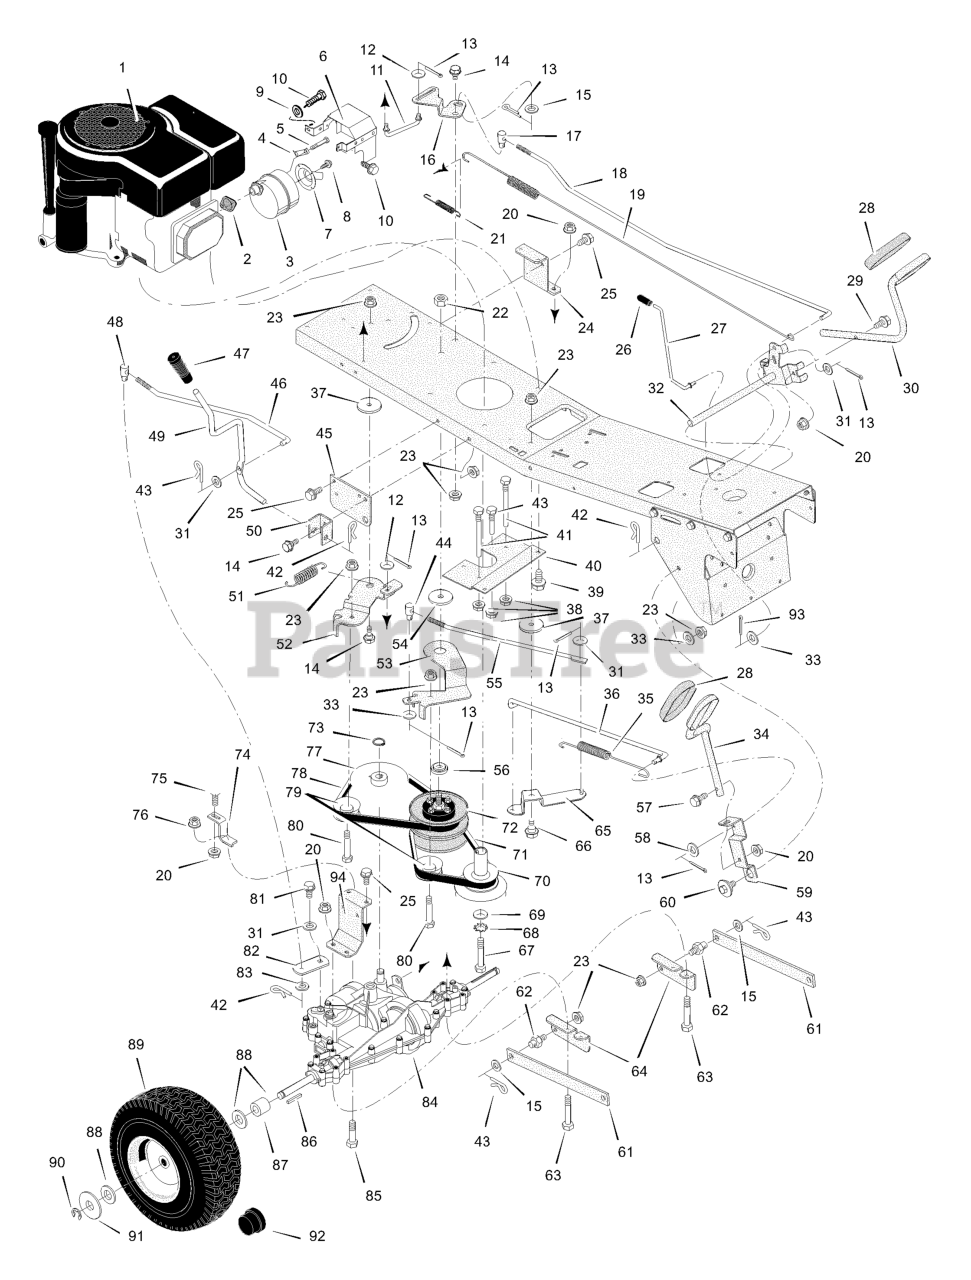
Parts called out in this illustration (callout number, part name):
1	Engine
2	GASKET, Exhaust
3	Muffler
4	Lock, Muffler Screw
5	Bolt, Hex
6	Shield, Heat
7	Tube, Exhaust
9	Washer, Lock
10	Screw
11	Rod, Link
13	Pin, Cotter
14	Bolt, Shoulder
15	Washer
16	Link, Clutch
17	NUT, Adjusting, 1/2-13
18	Rod, Clutch Variator
19	Spring, Brake
20	Nut
21	Spring, Brake Return
23	Nut
24	Bracket, Transaxle -Right
27	Rod, Parking Brake
28	Pad, Pedal
29	Bolt, Hex
30	Rod, Clutch/Brake
32	Rod, Clutch/Brake Pivot
33	Washer
34	Pedal, Variator
35	Spring, Return
36	Rod, Variator Connect
38	Nut
39	Screw
40	Plate, Belt Guide
41	Guide, Belt -Long
42	Pin, Hair
43	Guide, Belt -Short
44	Nut, Adjusting
45	Bracket, Lift Pivot
46	Rod, Shift Link
47	Grip
48	Nut, Adjusting
49	Lever, Shift
50	Bracket, Pivot
51	Spring - Variator Drive
52	Arm, Idler
53	Arm, Clutch Ider
55	Link, Drive
57	Bolt
58	Washer
59	Arm, Pedal
60	Bolt, Shoulder
62	Pin, Threaded
63	Bolt, Hex
64	Bracket, Rear Hanger
65	Link Assembly, Pivot
66	Bolt, Shoulder
67	Bolt, Hex
68	Lockwasher
70	Pulley Stack
71	Belt, Primary Drive
72	Pulley Assembly, Variator
73	Ring, Snap
74	Bracket, Torque Reactor
75	Bolt, Carriage
76	Nut, Stoverlock
77	Pulley, Transaxle
78	Belt, Secondary Drive
79	Pulley, Idler
80	Bolt, Hex
81	Cap Screw
82	Yoke, Shift
84	Transaxle
85	Bolt, Hex
86	Key, Square
87	SPACER, Rear Wheel
89	Wheel & Tire Assembly
92	Hub Cap
93	Pin, Cotter
94	Bracket, Transaxle -Left
